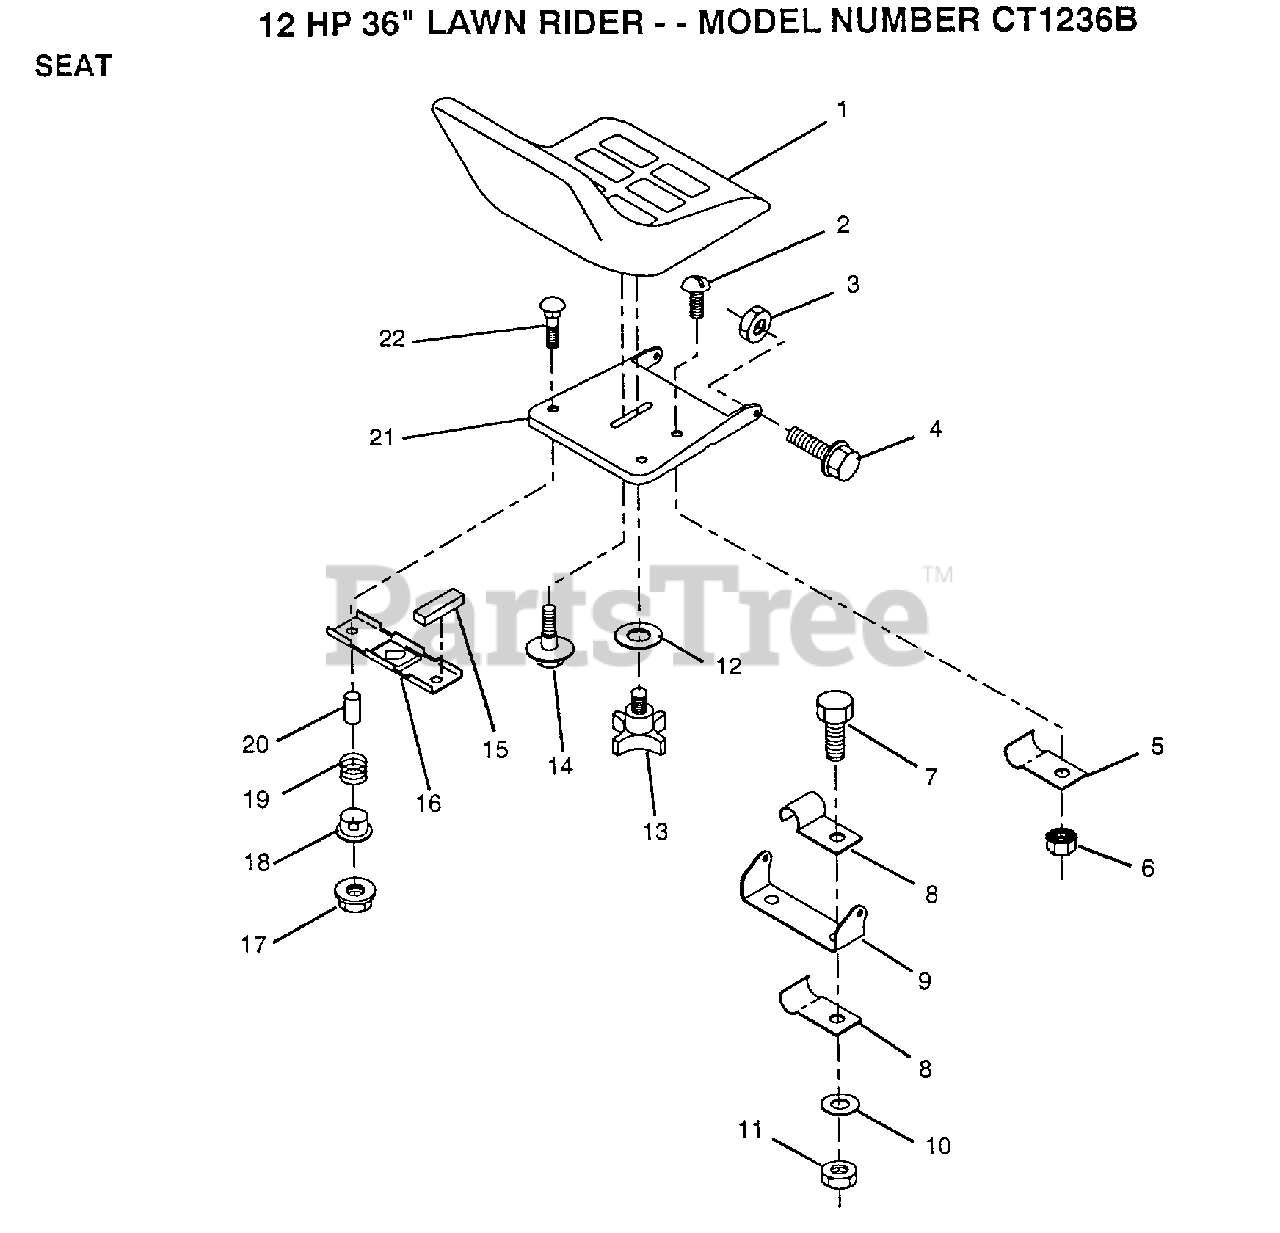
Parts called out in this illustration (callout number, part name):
6	"NUT,KEPS"
8	"CLIP,INSULATOR"
10	WASHER
12	WASHER
13	"KNOB 1/2"" YT"
14	"BOLT,SHOULDER"
15	STRIP FORM
16	BRKT SWITCH
18	BUSHING
19	SPRING
20	SPACER SPLIT
22	BOLT
